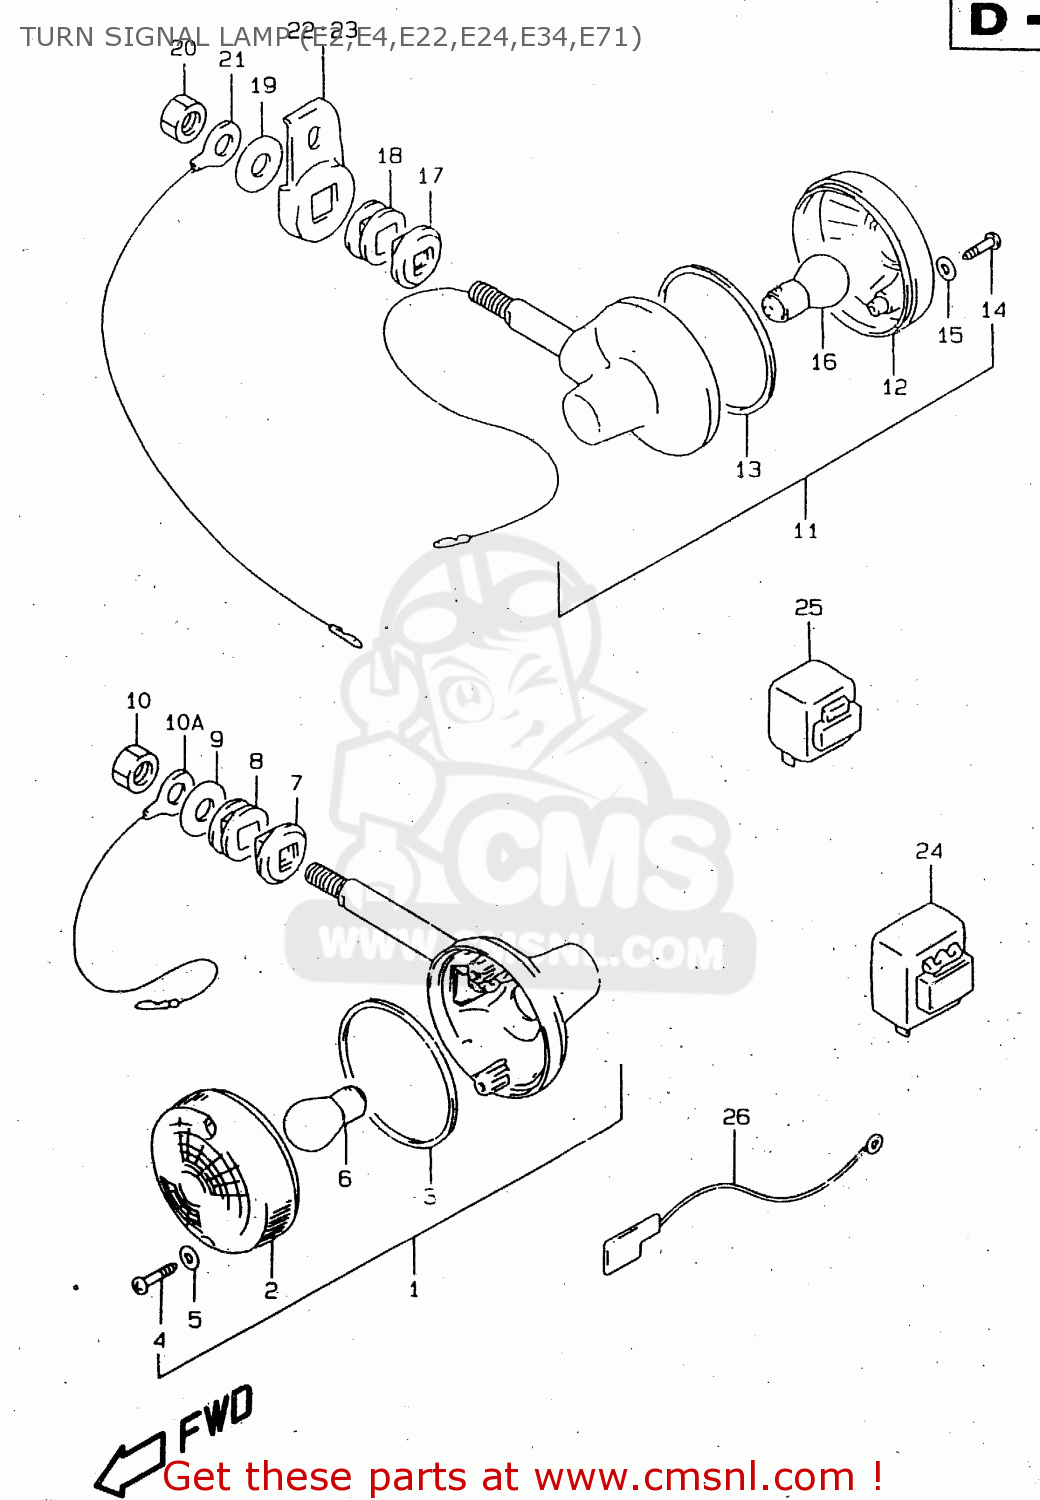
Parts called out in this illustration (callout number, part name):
1	LAMP ASSY,FR TURN SIGNAL
2	LENS
3	GASKET (NAS)
4	SCREW
5	GASKET (NAS)
6	BULB(12V21W)
7	SPACER
8	CUSHION
9	WASHER(10.5X30X2.3)
10	NUT
10A	LEAD WIRE,EARTH
11	LAMP ASSY,RR TURNSIGNAL
12	LENS
13	GASKET (NAS)
14	SCREW
15	GASKET (NAS)
16	BULB(12V21W)
17	SPACER
18	CUSHION
19	WASHER(10.5X30X2.3)
20	NUT
21	LEAD WIRE,EARTH
22	BRACKET,RR TURNSIGNAL LAMP,R
23	BRACKET,RR TURNSIGNAL LAMP,L
24	RELAY ASSY,TURNSIGNAL
25	RELAY ASSY,TURNSIGNAL
26	LEAD WIRE
